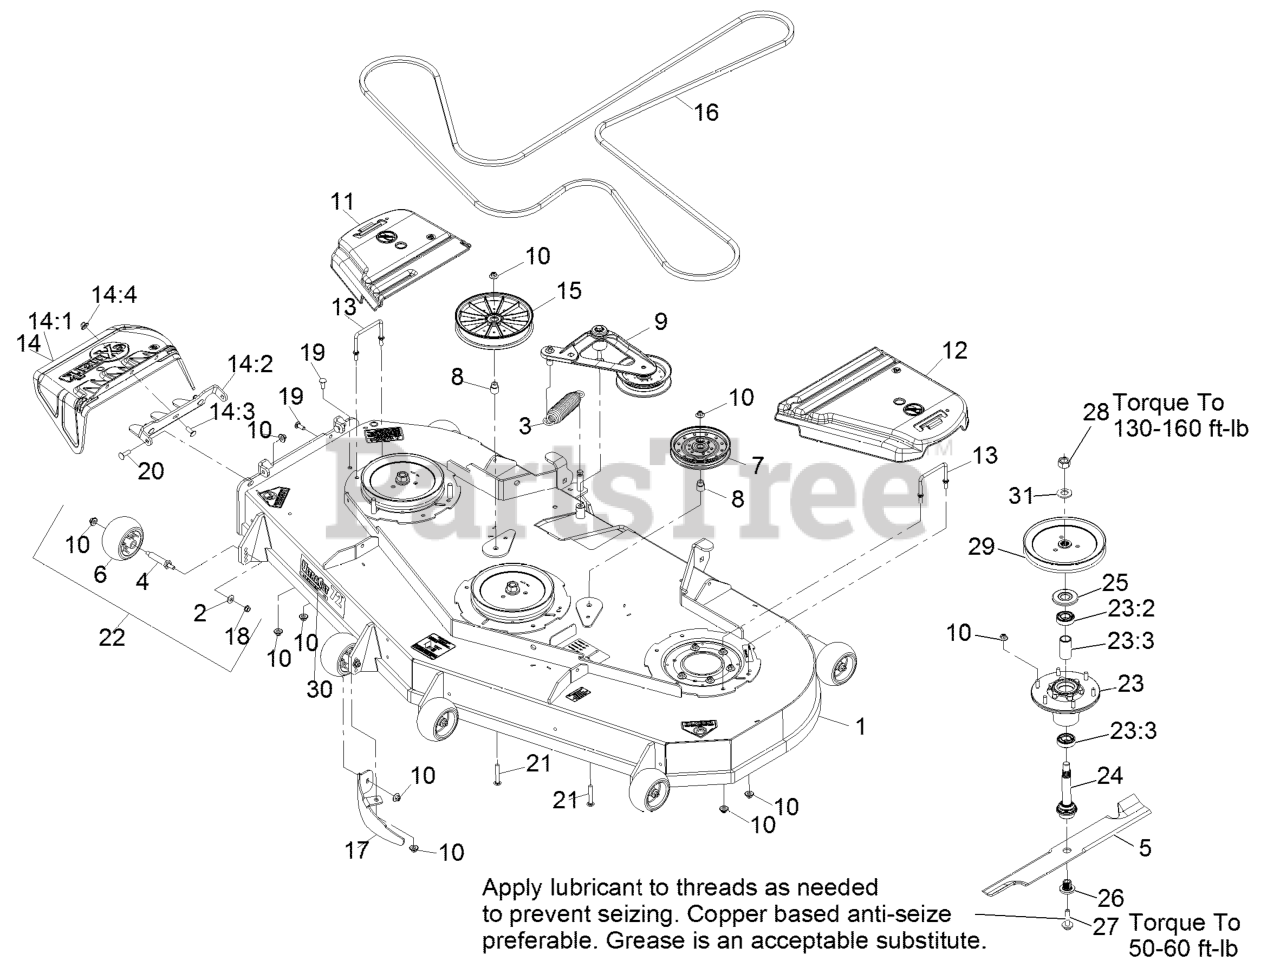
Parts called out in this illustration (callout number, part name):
1	ASM,DECK W/DECALS 724
2	WASHER-BELLEVILLE
3	SPRING-EXTENSION
6	ROLLER-SCALP, ANTI
8	BUSHING-IDLER
9	DECK IDLER ASM
10	Nut-Nyloc 3/8-16 Flg
11	COVER-BELT, RH
12	COVER-BELT, LH
13	WIREFORM-COVER
14	ASM,DISCHARGE CHUTE
14:1	CHUTE,DISCHARGE
14:2	BRACKET,DISCHARGE CHUTE
14:3	SCREW-CARR
14:4	Nut-Nyloc 3/8-16 Flg
15	PULLEY,IDLER 8"FLAT
16	BELT-V
17	BAFFLE-DOGLEG, LZ72
18	NUT-HHF, WHIZ
19	SCREW-CARR
20	Bolt-Carriage 3/8-16 X 1 1/4
21	SCREW-CARR
23	ASM-CUTTER HSG WITH BEARINGS
23:2	BEARING-BALL
23:3	SPACER-BEARING
24	ASM-SPINDLE AND SEAL
25	GUARD,BEARING TOP .989
26	BUSHING,SPLINED
27	SCREW,SEMS 1/2-20 X 2.19
28	NUT-HEX
29	SHEAVE,BLADE DRIVE 8.74
30	DECAL,ULTRACUT 72 SERIES
